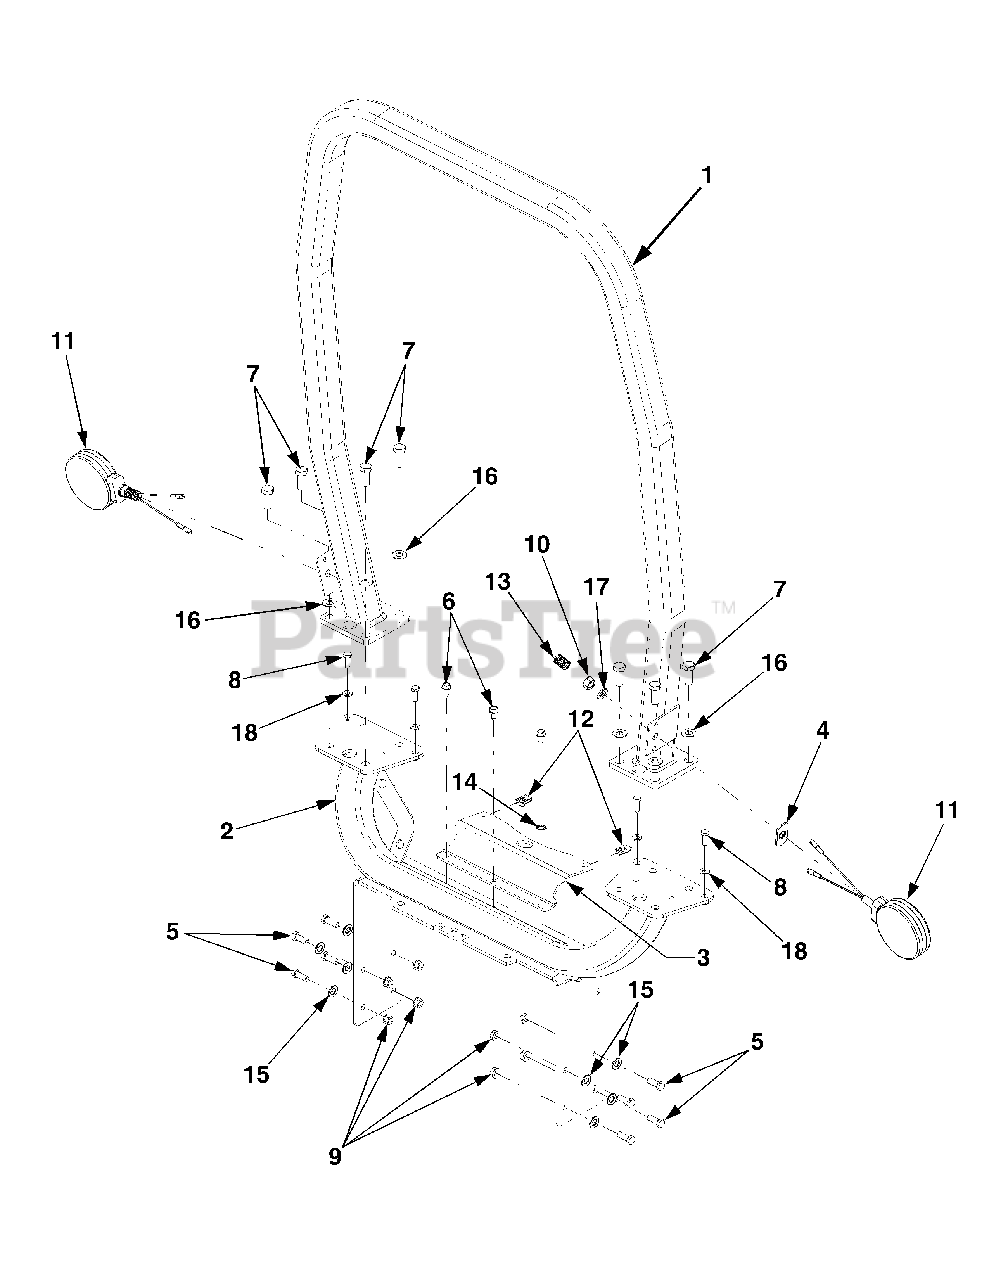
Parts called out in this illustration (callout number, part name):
1	Rops. Upper
2	Rops, Lower
3	Bracket, Rear Seat Mounting
4	Plate, Spacer
5	Screw, Hex Cap, 3/8-16 x 1.0 GR5 .
6	Screw, Hex Wash. Hd. Tapp 5/16-18 x .75
7	Screw, Hex Cap, 1/2-13 x 1.25 GR5
8	Screw, Hex Cap, 5/16-18 x .875 GR5
9	Nut, Hex Flange Lock, 3/8-16 GRF
10	Nut, Hex, 1/2-20 GR5
11	Light, Hazard
12	Nut, Speed, 5/16-18
13	Conduit, 12in
14	Washer, Ext. Tooth Lock, 3/8
15	Washer, Flat, .375 x .74x.063
16	Washer, Flat, .51 x 1.0 x .060
17	Washer, Lock, 1/2
18	Washer, Flat, .345 x 1.0 x .10
